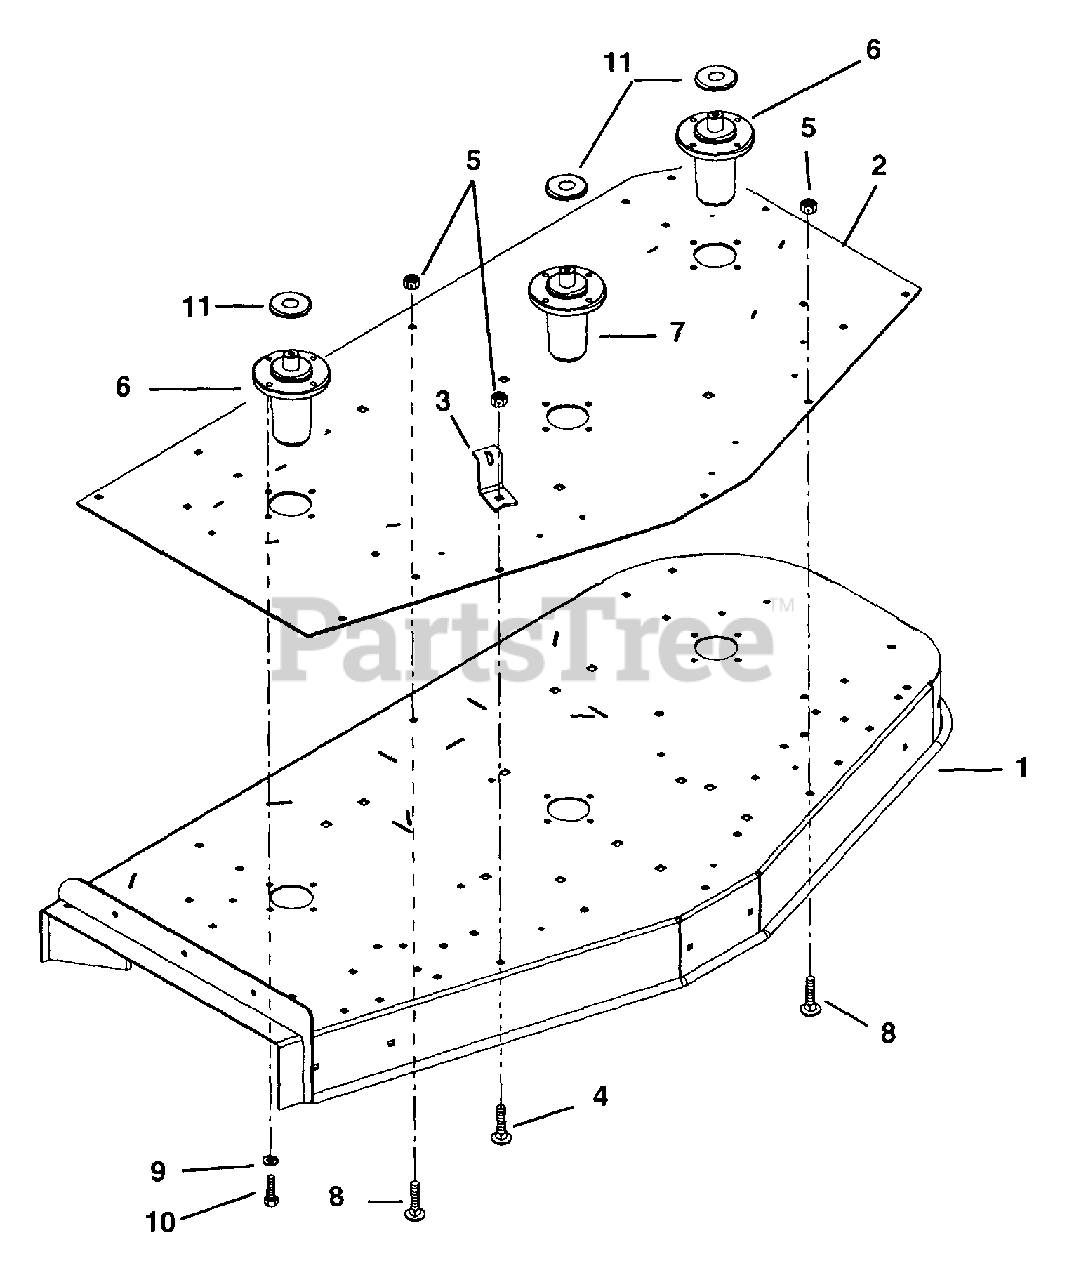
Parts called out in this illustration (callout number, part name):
1	Weldment, 60" Deck (Side Discharge)
2	Plate, 60" Reinforcing
3	Spring, Bracket
4	Bolt-Round Head Square Neck .38-16 x 1.25 Grade 2
5	Nut-Locking-Nylon .38-16
6	Assembly, Spindle L-Hub
7	Assembly, Spindle
8	Bolt-Round Head Square Neck .38-16 x 1.00 Grade 2
9	Washer-Locking .38 x .094
10	Bolt-Hex,38-16 x 1.00 Grade 5
11	Slinger-Dust
